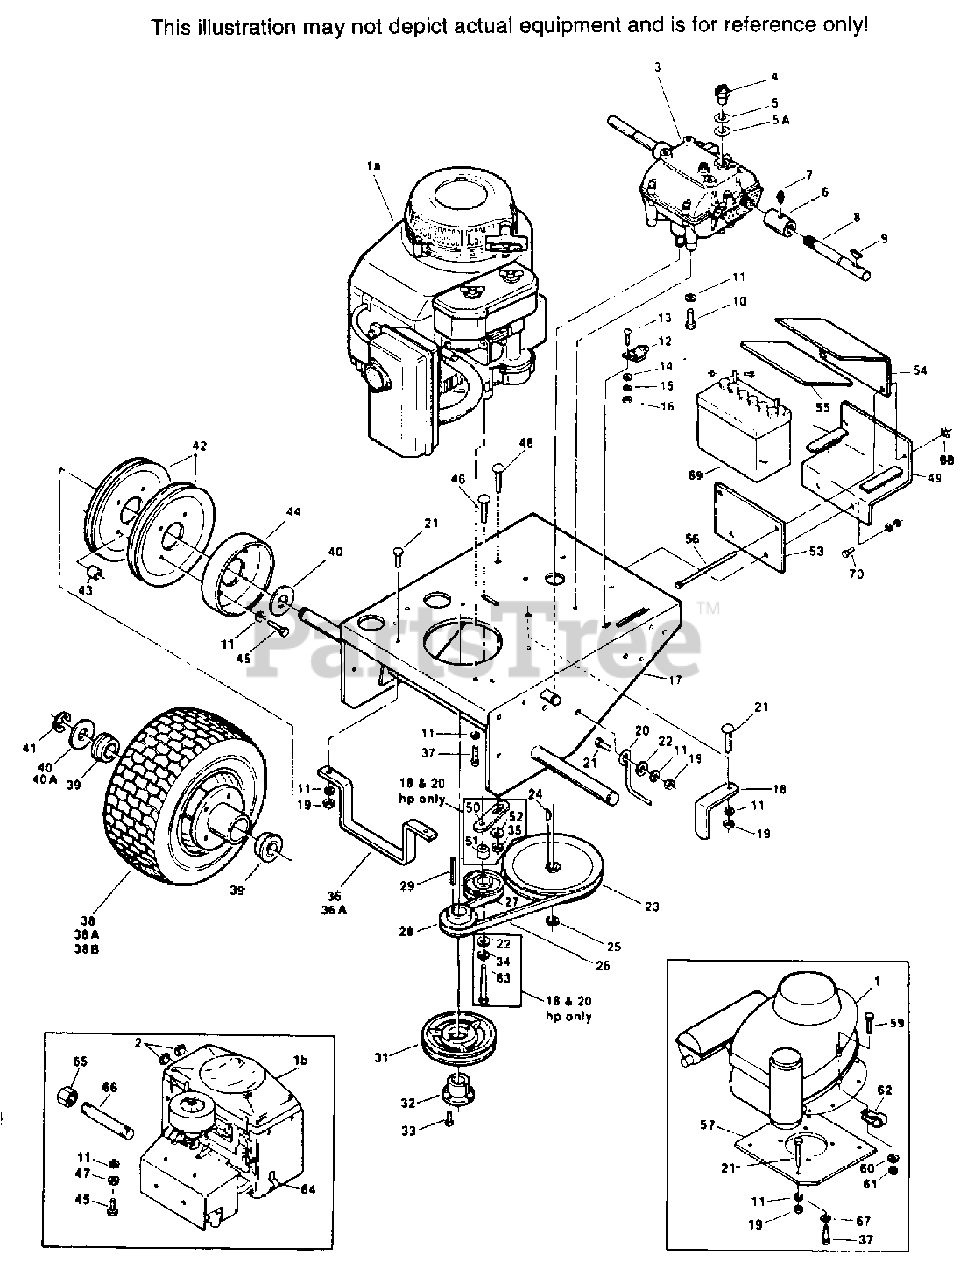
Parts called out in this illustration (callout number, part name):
3	TRANSMISSION 5 SPD(PEERLESS 700-026)
3	TRANSMISSION 4 SPD(PEERLESS 700-022)
4	NEUTRAL SAFETY SWITCH
5	FIBRE WASHER, THIN
5A	FIBRE WASHER, THICK
6	COUPLER, JACKSHAFT
7	GREASE FITTING, STRAIGHT 1/4-28
8	JACKSHAFT(FITS SW32, 36, & 48)
9	KEY, HI-PRO #9
12	SWITCH, CLUTCH SAFETY BLACK
15	LOCKWASHER, #10 EXT. TOOTH
17	ENGINE DECK(FITS SW36, & 48)
18	REAR BELT GUIDE, ENGINE
20	BELT GUIDE, TRACTION DR.
22	WASHER, 25/64 X 15/16 X 12 GA.
23	PULLEY, TRANSMISSION INPUT
24	KEY, WOODRUFF #9
25	RETAINING RING, 5/8 EXT. BASIC
26	BELT, TRANSMISSION DRIVE
27	IDLER PULLEY, TRANSMISSION
36	BELT GUIDE, SADDLE(FITS SW32, & 36)
38	WHEEL ASSY(INCL. 38A-38B)(FITS SW36, 48,
38A	TIRE, 13 X 6.50-6, 2-PLY FITS SW36, 48, 52,
38B	RIM & BRG ASSY(INCL. 39) FITS SW36, 48, 52,
39	WHEEL BEARING NWC(OD 1.984 - 1.980)
39	WHEEL BEARING(OD 2.000 - 2.005)
40	WASHER, 1-1/16 X 1-3/4 X 12 GA.
40A	WASHER, 1-1/16 X 1-1/2 X 18 GA.
41	RETAINING RING, 1" EXT.-"E"
42	PULLEY, WHEEL DRIVE
43	SPACER, WHEEL PULLEY
44	BRAKE DRUM
46	SHORT SQUARE NECK CRG. BOLT, 3/8-16 X 2
47	HEX NUT, 5/16-18 ELASTIC STOP
